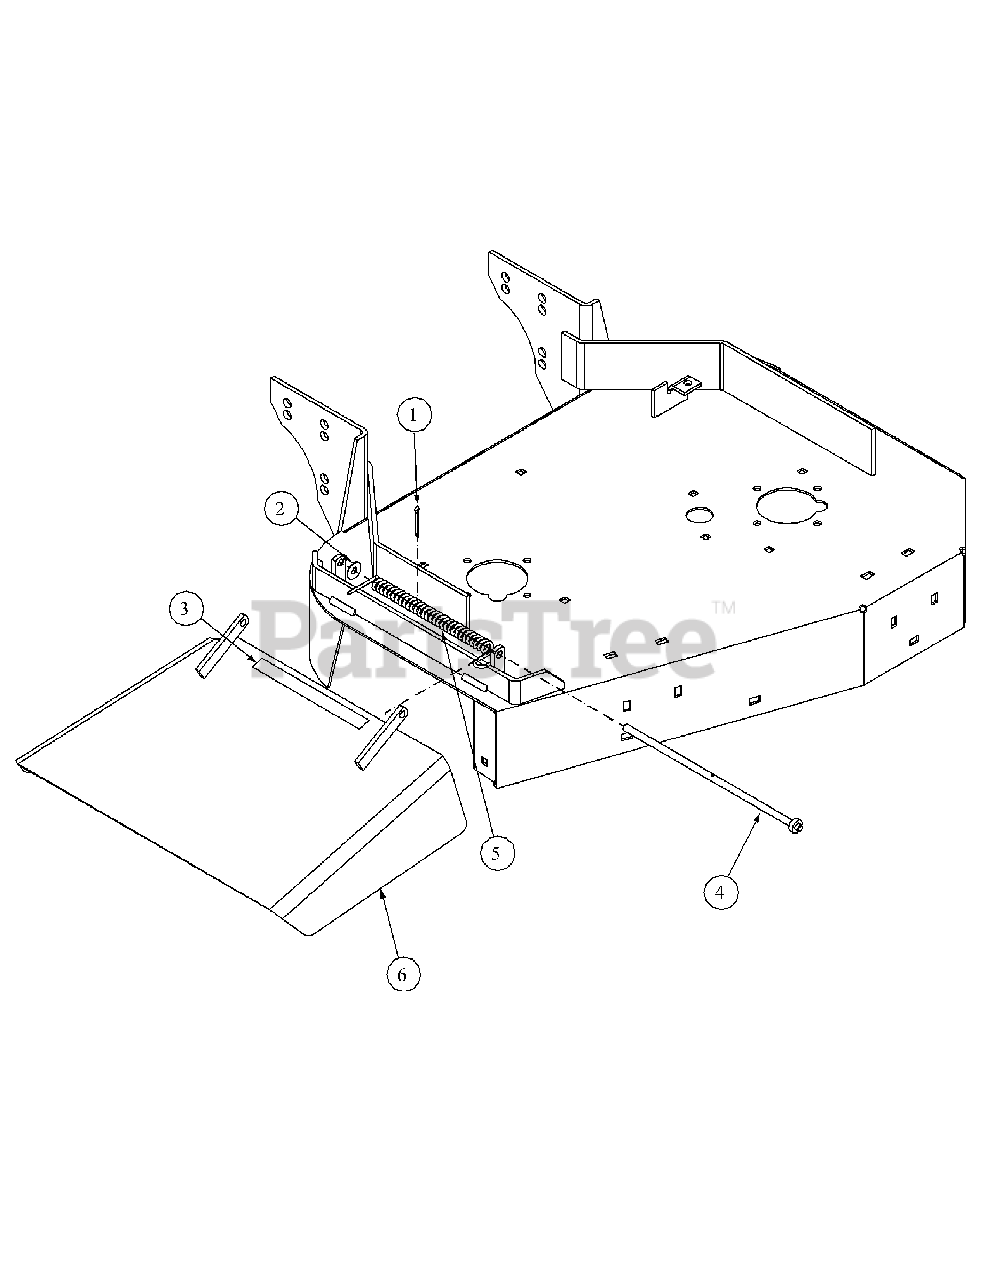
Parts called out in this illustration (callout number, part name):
1	Cotter Pin, 5/32 x 1 1/2 Zinc
2	Flat Washer, 3/8, Zinc
3	Decal, Cut Line
4	Pin, Deflector Assembly, Weldment
5	Torsion Spring
6	Chute Assembly Discharge
